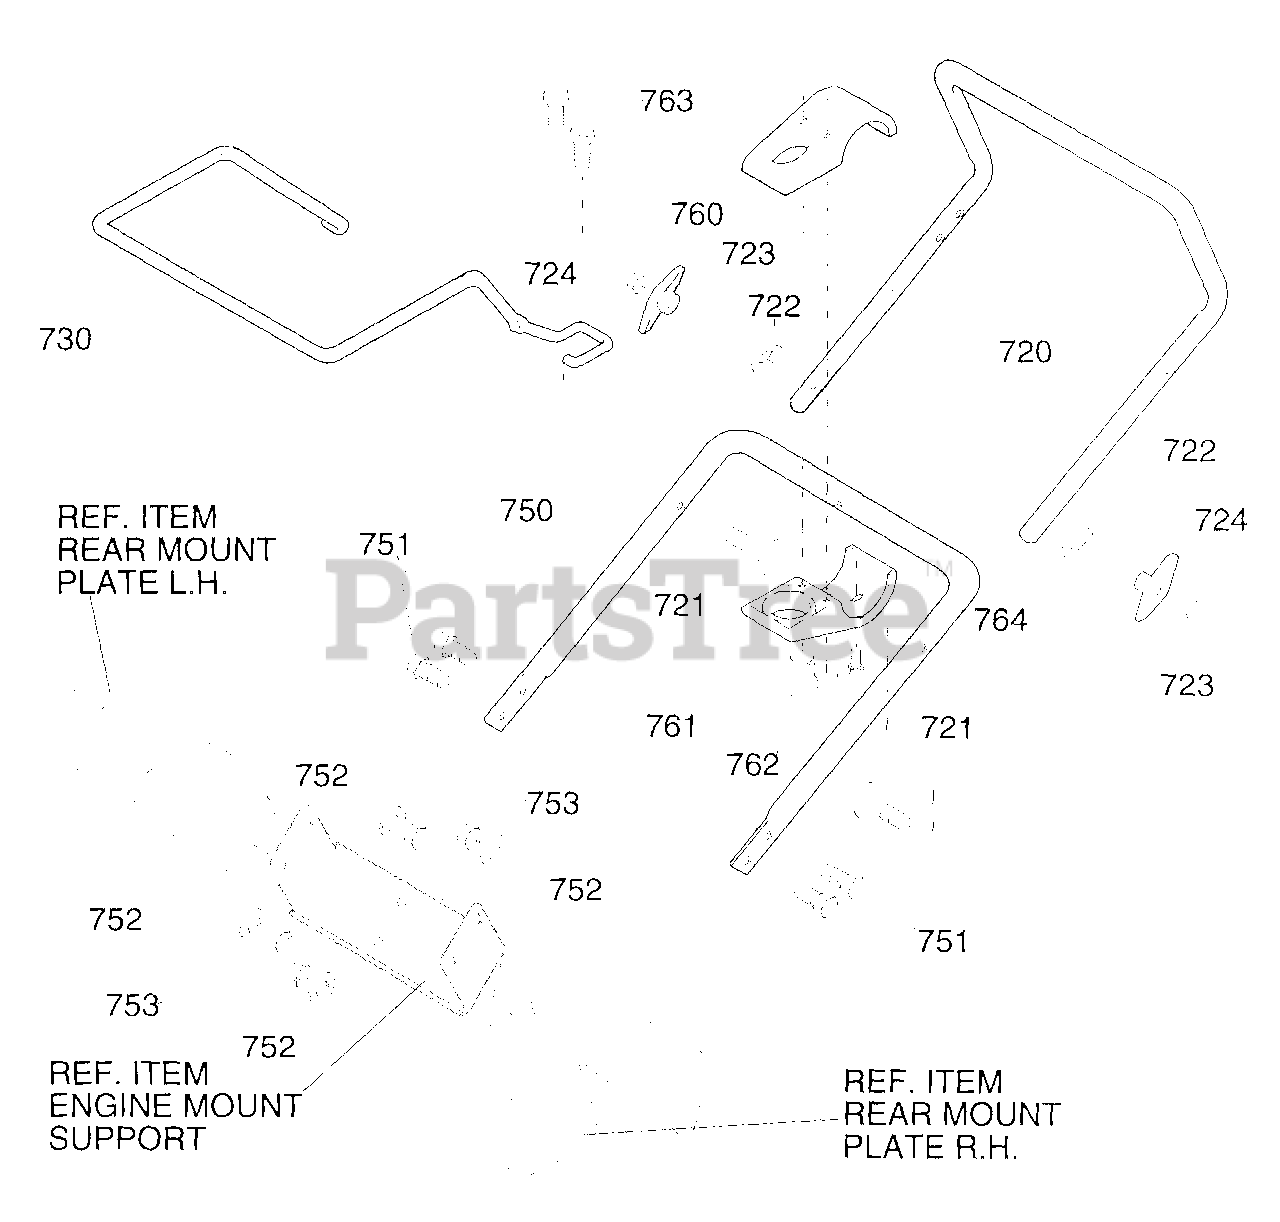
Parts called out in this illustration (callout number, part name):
720	HANDLE, UPR .88 X 18 GA
721	BOLT, 5/16-18 X 1.75
722	WASHER, FORM .344 ID 1.0 OD
723	KNOB, T 2BLADE W/NUT
724	NUT, 5/16-18 REGHEX
730	BAR, CONTROL DRIVE .31 DIA
750	HANDLE, LWR
751	SCREW, 5/16-18 X .75 HHC
752	WASHER, FLAT
753	NUT, 5/16-18 REGHEXCTRLK
760	BRKT HALF, CHUTE CRANK
761	BRKT HALF, CHUTE CRANK
762	NUT, #10-24 HEXNYLK
763	SCREW, #10-24 X 1.00
764	SCREW, 1/4-20 X .63
